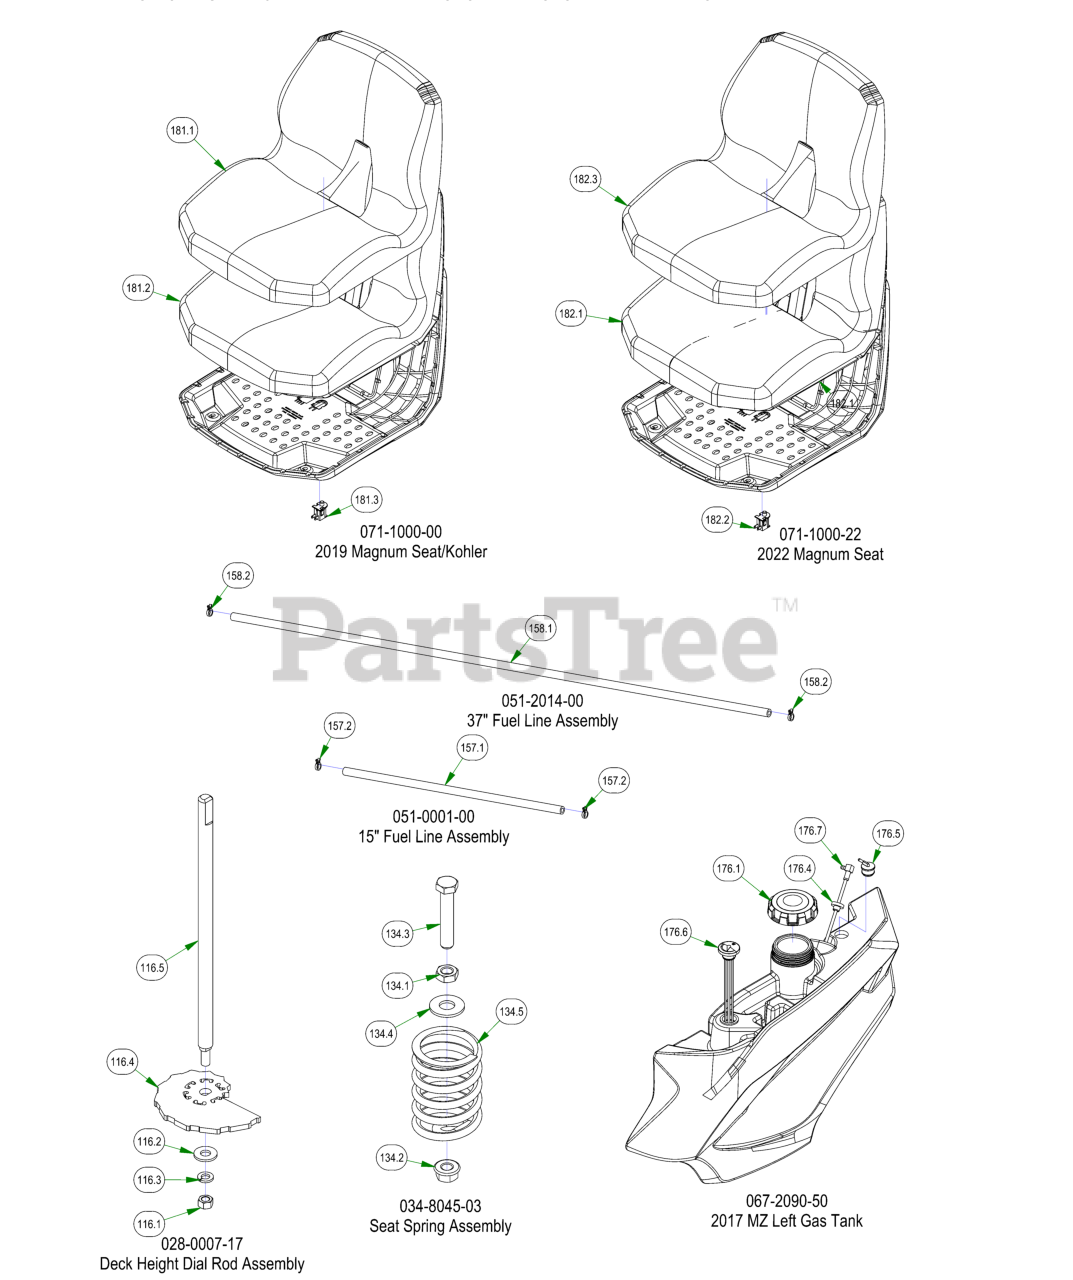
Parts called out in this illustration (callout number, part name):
116	Deck Height Dial Rod Assembly
116.1	3/8" Fine Threaded Jam Nut
116.2	3/8" Flat Washer
116.3	3/8" Lock Washer
116.4	2017 MZ/ZT Cam Plate
116.5	2017 Deck Height Dial Rod MZ
134	Seat Spring Assembly
134.1	3/8-16 Half Jam Nut
134.2	3/8-16 HEX SERRATED FLANGE NUT HARD/ZINC
134.3	3/8-16 X 2 HEX CAP SCREW (GR.5) ZINC
134.4	3/8 FLAT WASHER USS (1" OD) ZINC
134.5	Seat Spring
157	15" Fuel Line Assembly
157.1	1/4 Fuel Line
157.2	1/4 Fuel Hose Clamp
158	37" Fuel Line Assembly
158.1	37" 1/4 Fuel Line
158.2	1/4 Fuel Hose Clamp
176	2017 MZ Left Gas Tank
176.4	Pick-Up Grommet
176.5	Rollover Valve W/Grommet
176.6	Fuel Gauge w/Grommet
181	2019 Magnum Seat/Kohler
181.1	Seat Cover for 071-1000-00
181.2	Seat Foam for 071-1000-00
181.3	SeatSwitch for 071-1000-00/071-1000-22/071-2100-22
182	2022 Magnum Seat
182.1	SK120 Seat Foam for 071-1000-22
182.2	SeatSwitch for 071-1000-00/071-1000-22/071-2100-22
182.3	Bad Boy SK120 Cover with Logo for 071-1000-22
